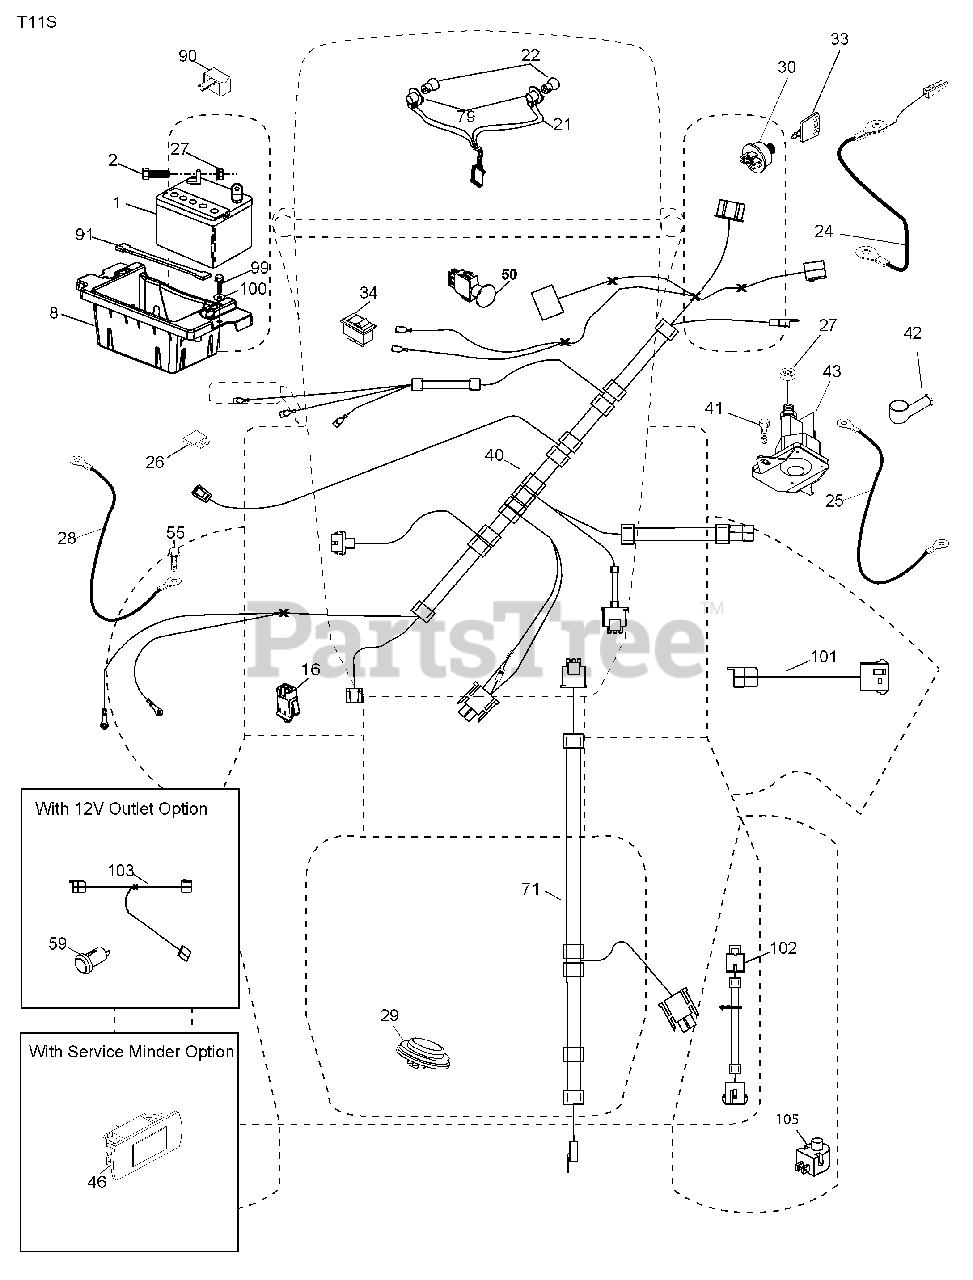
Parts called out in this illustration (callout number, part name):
1	Battery
2	Bolt Hex Hd 1/4-20 unc x 3/4
8	Battery Box
16	Switch Interlock
21	Harness Socket Light
22	Bulb, Light #1156
24	Cable Battery
25	Cable Starter
27	Nut Keps Hex 1/4-20 unc
28	Cable Ground 21" Blk 6 Ga.
29	Switch Seat
30	Switch Ign
34	Switch Light/Reset
40	Harness Ign. Dash
41	Screw Thd Cut 1/4-20 x 1/2
42	Cover Terminal Red
43	Solenoid
46	Gauge Hourmeter
50	Switch PTO
55	Screw Thdrol 5/16-18 x 3/4
59	Outlet 12-Volt
71	Harness Ign
79	Socket Asm. Bulb Twistlock
90	Cover Terminal Battery
91	Strap Battery
99	Screw Hexwsh Thdrol 1/4-20 x 3/4
100	Washer 9/32 x 7/8 x 16 Ga.
101	Pigtail Malnlk
102	Harness Pigtail
103	Harness Pigtail
105	Switch Reverse TT Pedal Control
